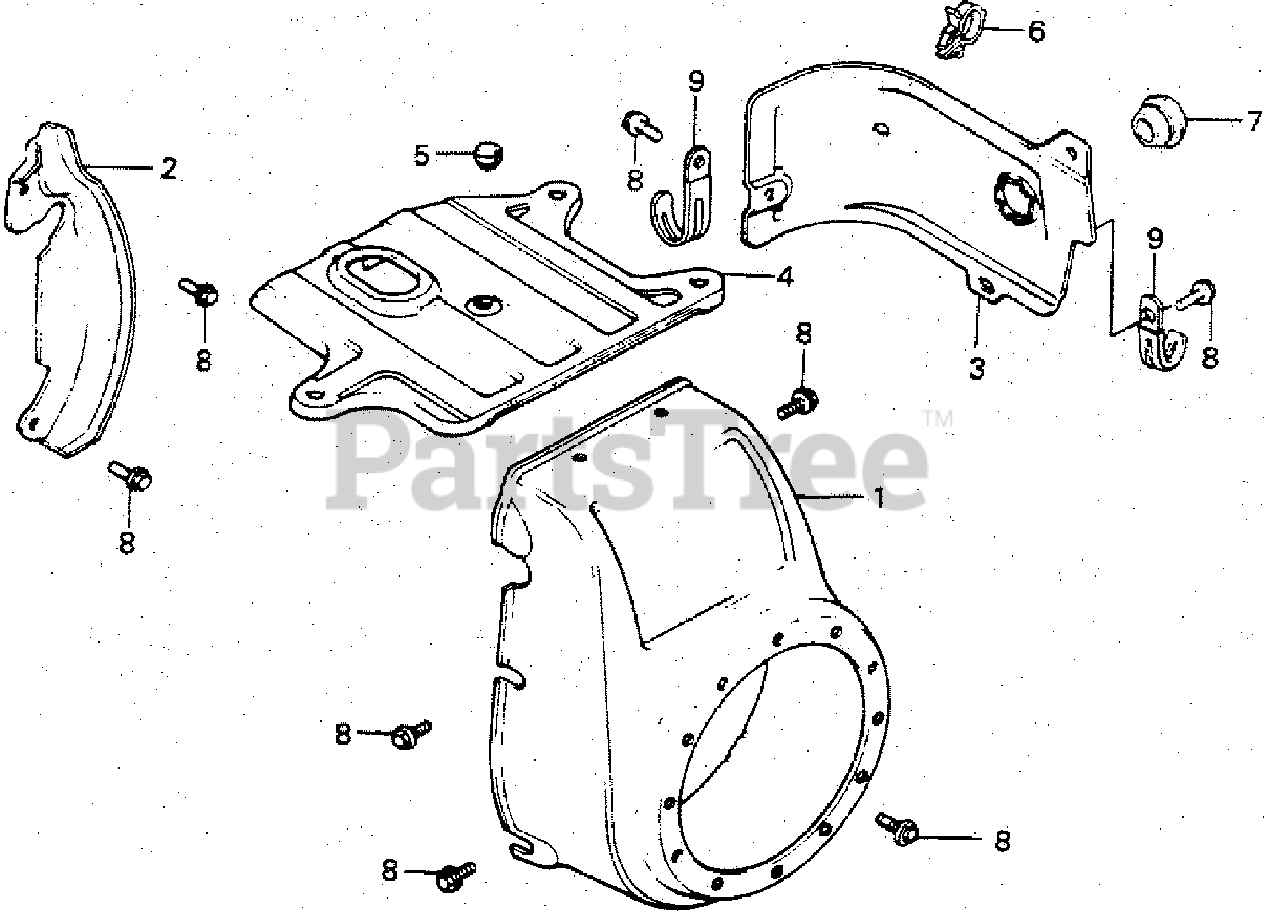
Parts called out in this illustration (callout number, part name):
1	COVER, FAN *R8* (BRIGHT RED)
2	PLATE, SIDE
4	COVER, TOP
5	GROMMET, TOP COVER
6	CLIP, IGNITION WIRE (8MM)
7	GROMMET, DRAIN HOLE
8	BOLT, FLANGE (6X12) (CT200)
9	CLIP, CABLE
